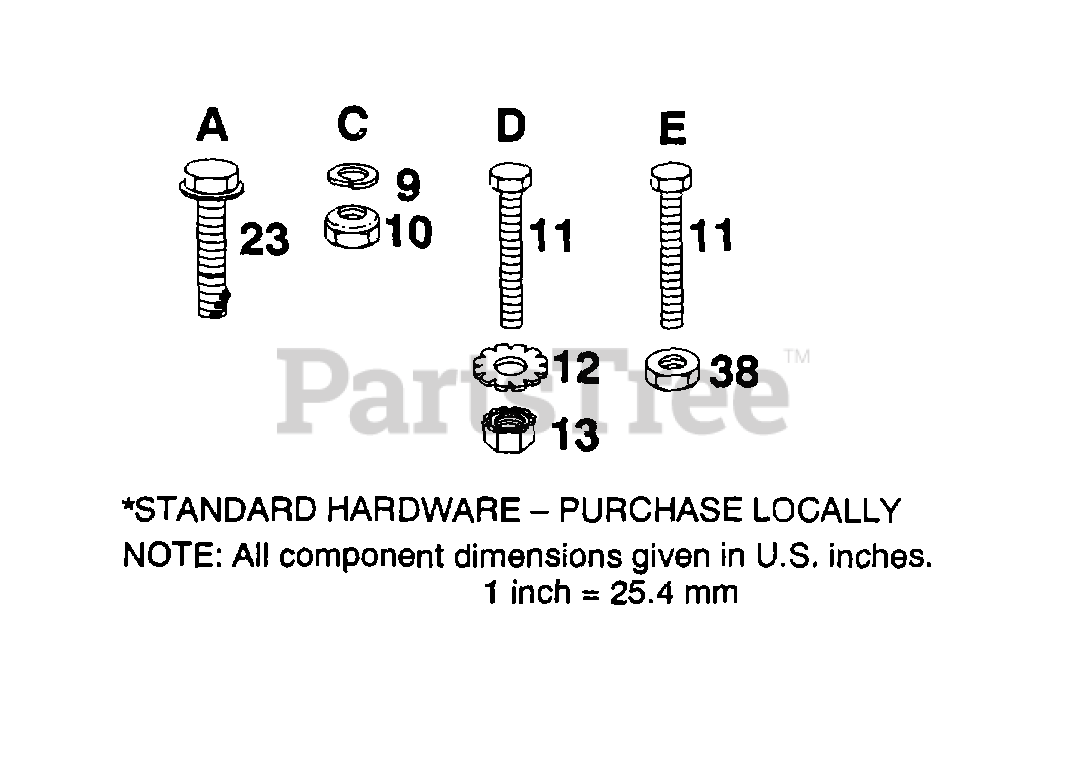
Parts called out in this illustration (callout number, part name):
10	NUT
11	BOLT
13	NUT
23	SCREW
